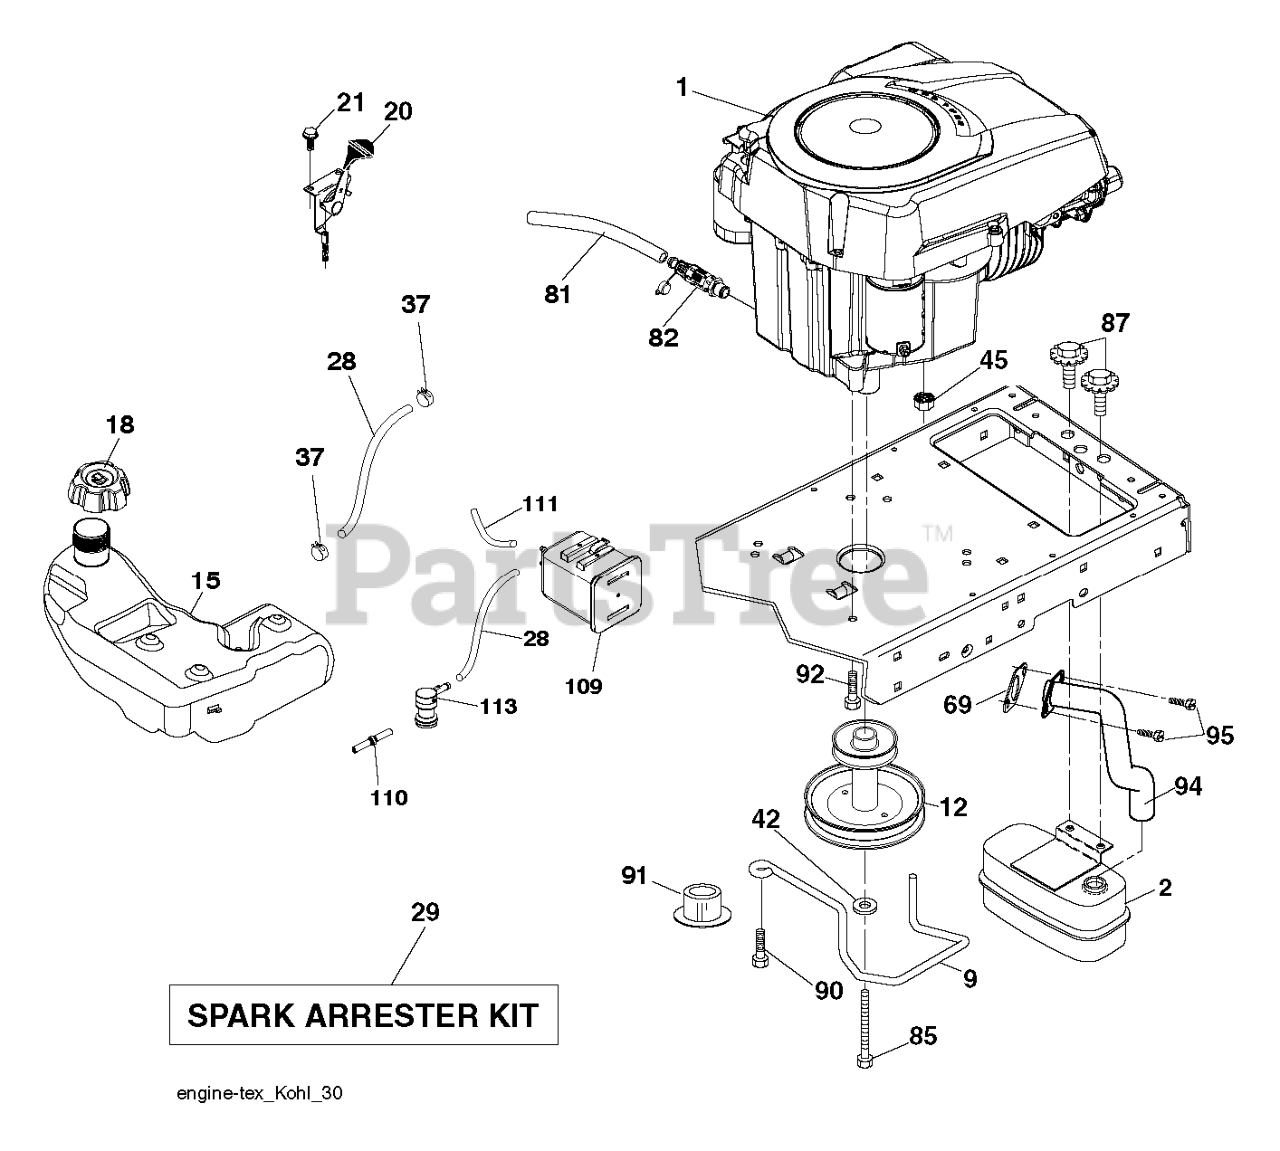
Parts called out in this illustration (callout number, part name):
2	MUFFLER.SINGLE.CYL.KOHL/B&S
9	KEEPER.BELT.ENGINE.4.2
12	RP_PULLEY ENGINE
15	TANK.ASM.FUEL.3GA.CARB
18	RP CAP ASM
20	CONTROL.TH/CK.COBRA.KO
21	SCREW.#10 X 0.750.BOS
28	LINE.FUEL.20"FRONT.EMI
29	KIT.SPARK ARRESTOR 794945 B&S
37	HOSE CLAMP
42	LOCKWASHER
45	NUT
69	GASKET.EXHAUST.KOHLER
81	TUBE, DRAIN OIL ASM.
82	VALUE.OIL.DRAIN
85	BOLT HEX 7/16-20X4-1/4"
87	BOLT 5/1618UNC X 3/4 W/ SEMS
90	SCREW 3/8-16X1
91	BUSHING.1.375OD
92	SCREW 3/8-16X1
94	RP.TUBE.EXHAUST.KOHL.COURAGE
95	SCREW.SOCKET HD.5/16-1
109	CANNISTER, CARBON
110	VALVE.ASM.ANTI-SLOSH
111	PURGE.LINE.36"REAR.CALIFORNIA
113	VALVE.SLANT.CARTRDG.90 DEG.TEX
